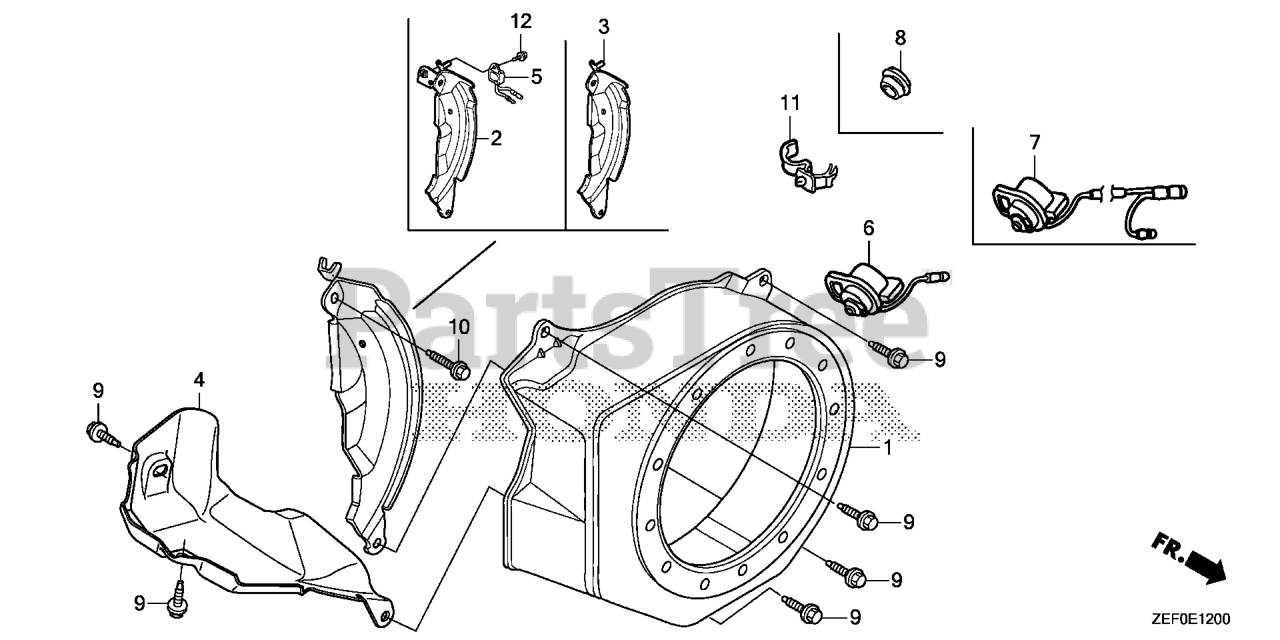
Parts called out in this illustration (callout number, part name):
1	COVER, FAN *R280* (POWER RED)
1	COVER, FAN *NH1* (BLACK)
2	PLATE, SIDE (OIL ALERT)
4	SHROUD
5	ALERT UNIT, OIL
7	SWITCH ASSY., ENGINE STOP
9	BOLT, FLANGE (6X12) (CT200)
10	BOLT, FLANGE (6X20) (CT200)
11	CLIP, HARNESS
12	BOLT, FLANGE (6X8)
